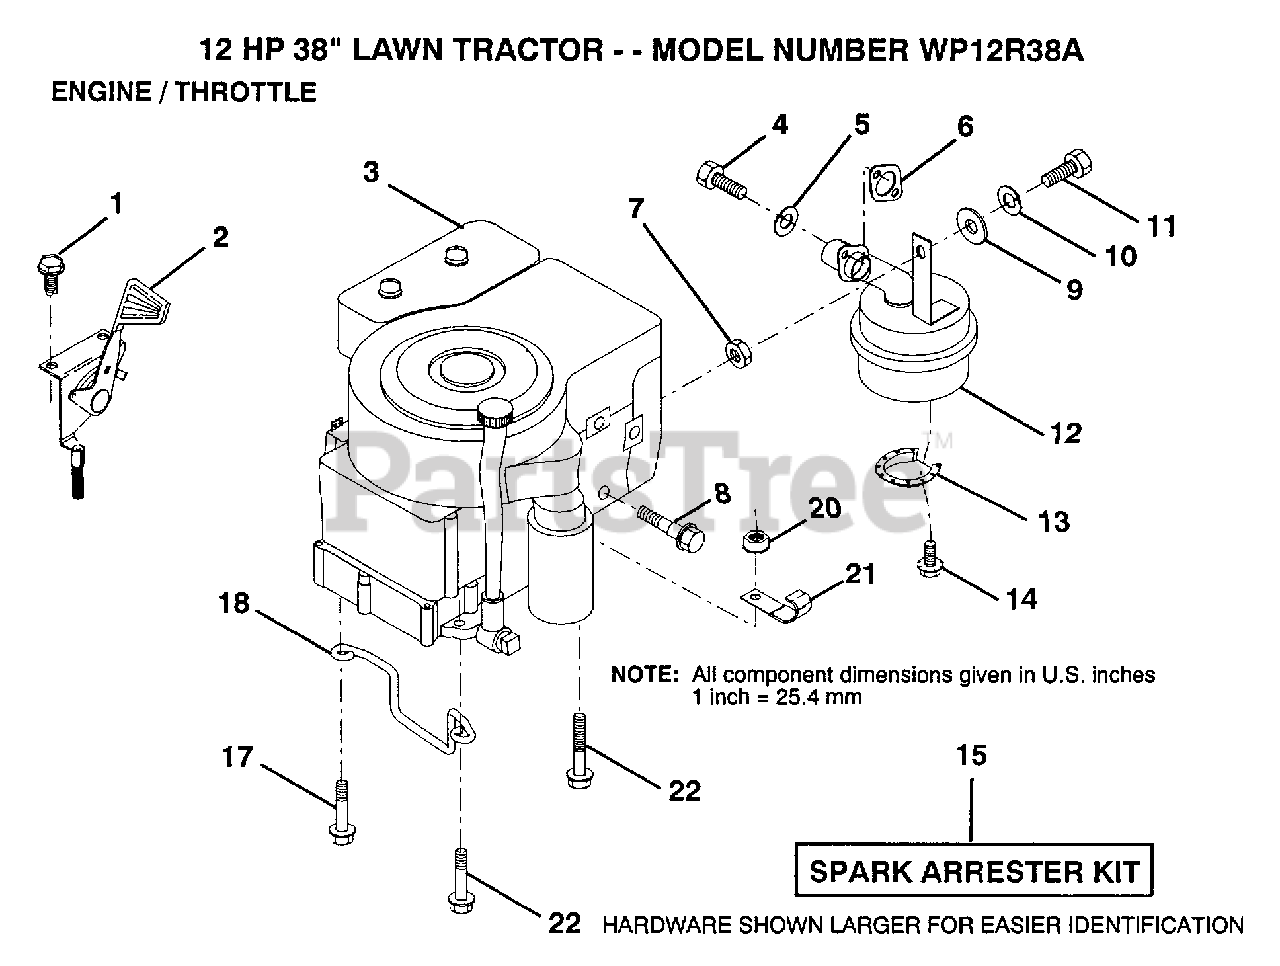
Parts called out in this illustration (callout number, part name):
1	SCREW
2	THROTTLE CONTROL
4	SCREW
5	LOCKWASHER
7	NUT.HEX.5/16-18
8	BOLT T
10	LOCKWASHER
12	MUFFLER
13	DEFLECTOR.222573
17	SCREW LT
18	"KEEPER,DR BELT GR"
20	NUT
21	CLIP T
22	SCREW LT
